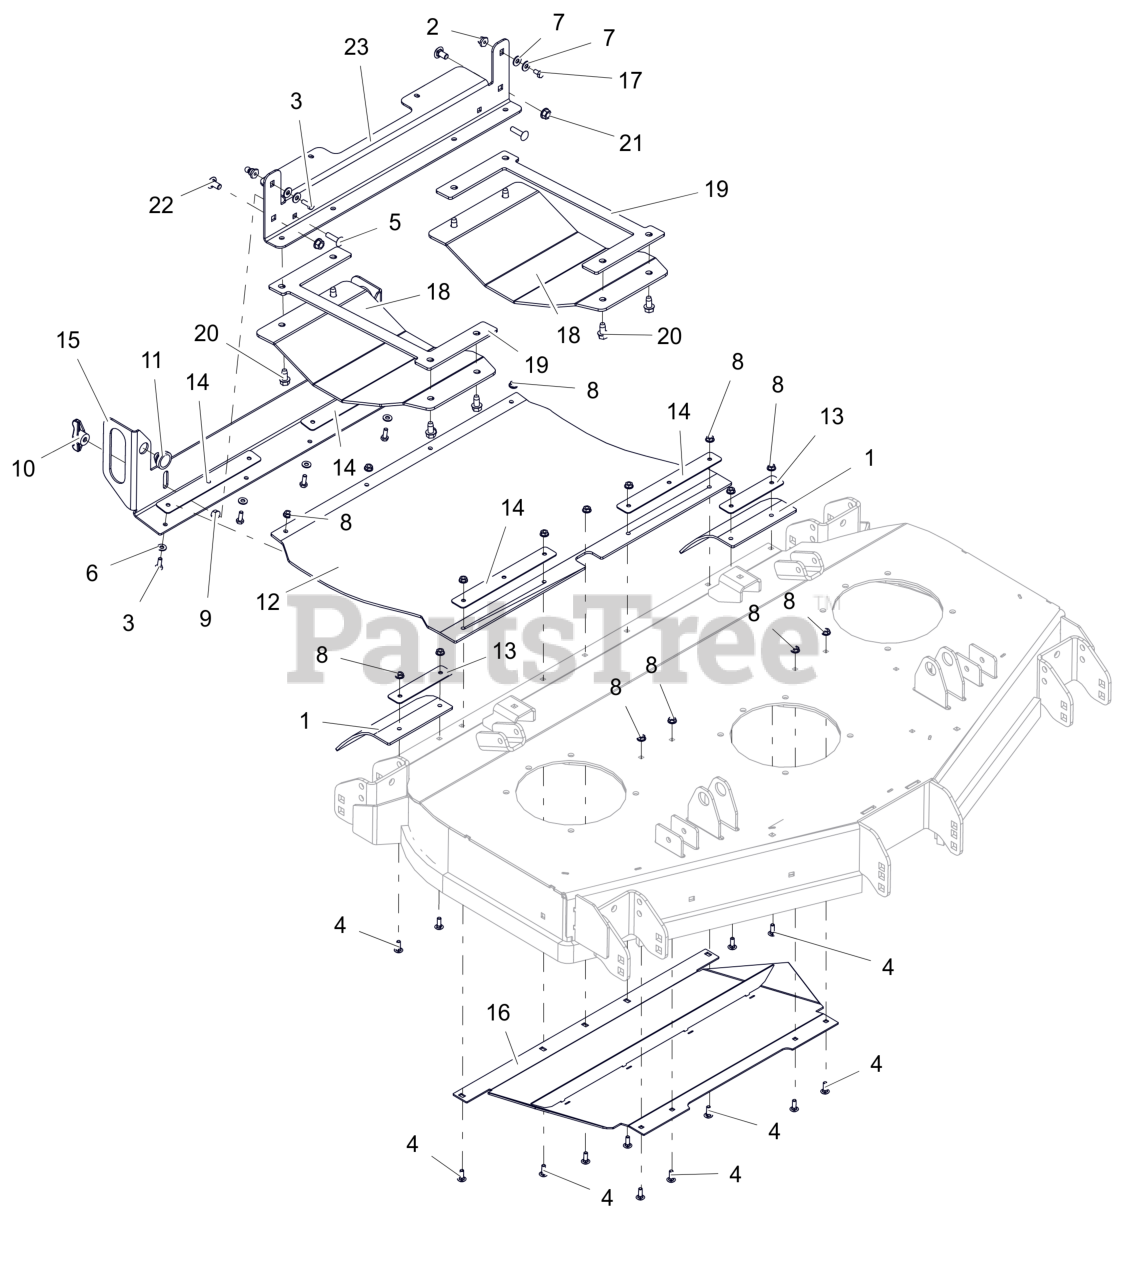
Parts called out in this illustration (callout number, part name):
1	FLAP, REAR DISCHARGE 48" TIRE
2	STUD, BALL FEMALE .250-20 THREAD
3	BLT, HEX .25-20X.75 G5 ZCC
4	BLT, RHSN .25-20X.750 G5 ZCC
5	BLT, RHSSN.31-18X1.25 G5 ZCC
6	WSHR,FLT .281X.625X.065 ZCC
7	WSHR, FLT .312X.734X.065 ZCC
8	NUT-LK-CTR-FLG .25-20 ZC120
9	NUT,LK-CTR-FLG .31-18 GF ZCC
10	KNOB,WING .31-18 UNC NYL/TALC
11	COUPLING, RUBBER PUSH-IN
12	CHUTE, REAR DISCHARGE
13	PLATE, 52" TIRE CHUTE MTG (BLACK)
14	PLATE, CHUTE MTG (BLACK)
15	HANDLE, CHUTE MOUNTING (ORANGE)
16	WLDMT, DEFLECTOR BAFFLE (ORANGE)
17	BLT,HEX .25-20X.50 G5 ZCC
18	PLATE, SKID (BLACK)
19	PLATE, SKID TENSION (BLACK)
20	SCR,TAP .375-16X.75 HWH TR ZCC
21	NUT-LK-CTR-FLG .375-16 GF ZCC
22	BLT, RHSSN .38-16X.75 G5 ZCC
23	BRKT, SKID PLATE MTG. (ORANGE)
